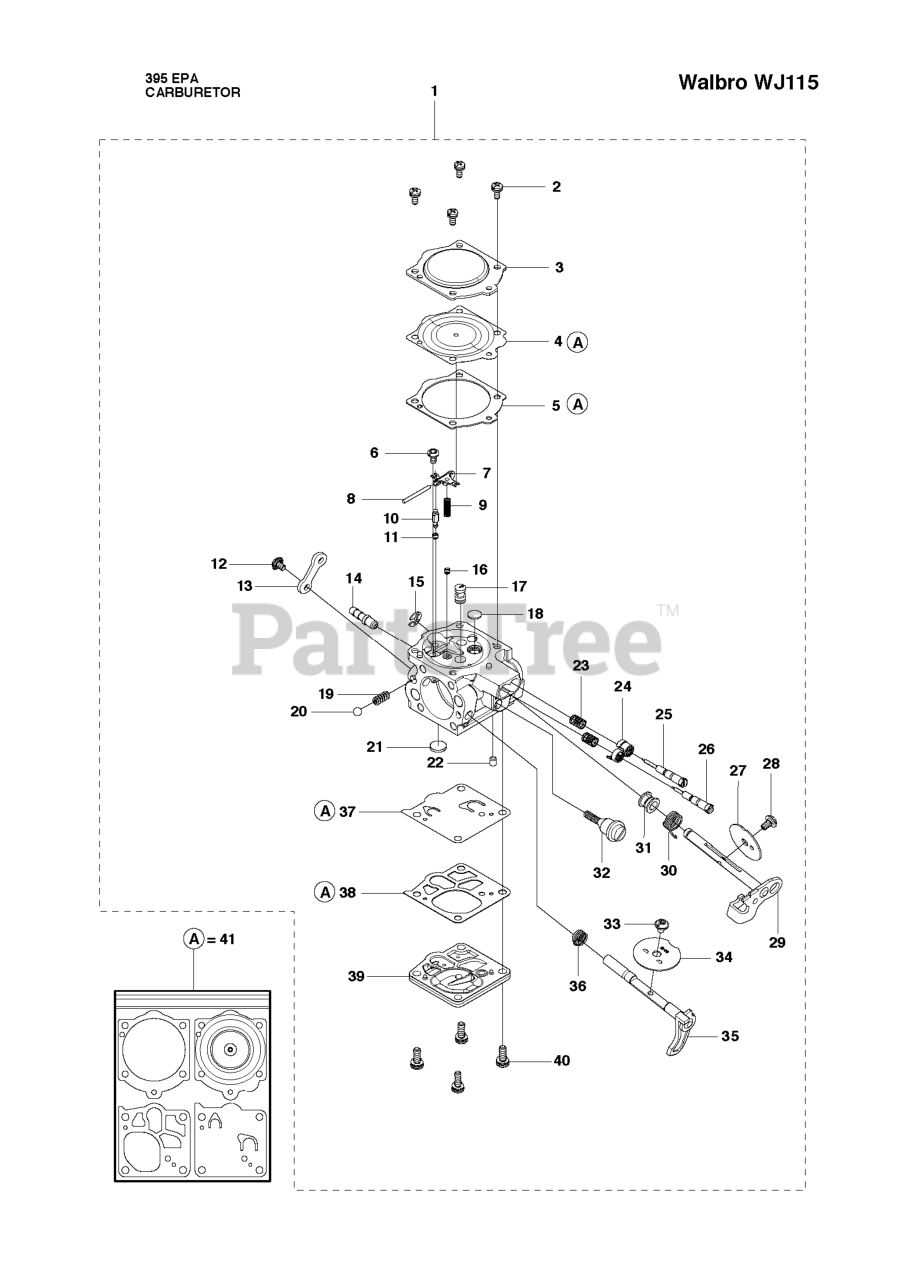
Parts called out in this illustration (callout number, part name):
1	CARBURETOR
2	RP SCREW W/ WASHER
3	DIAPHRAM COVER
4	MAIN DIAPHRAGM
9	SPRING METERING
10	INLET NEEDLE
11	SEAT IN VALVE PLATED
14	FITTING FUEL INLET
15	E CLIP
18	PLUG WELCH
21	FUEL INLET SCREEN
22	PLUG FRICTION
24	LIMITER CAP
27	THROTTLE FLAP
29	SHAFT ASSY THROTTLE
33	SCREW
34	CHOKE FLAP
35	SHAFT ASSY
36	SPRING CHOKE
37	DIAPHRAM PUMP
39	COVER PUMP
40	SCREW W/ WASHER
41	DIAPHRAGM SET
